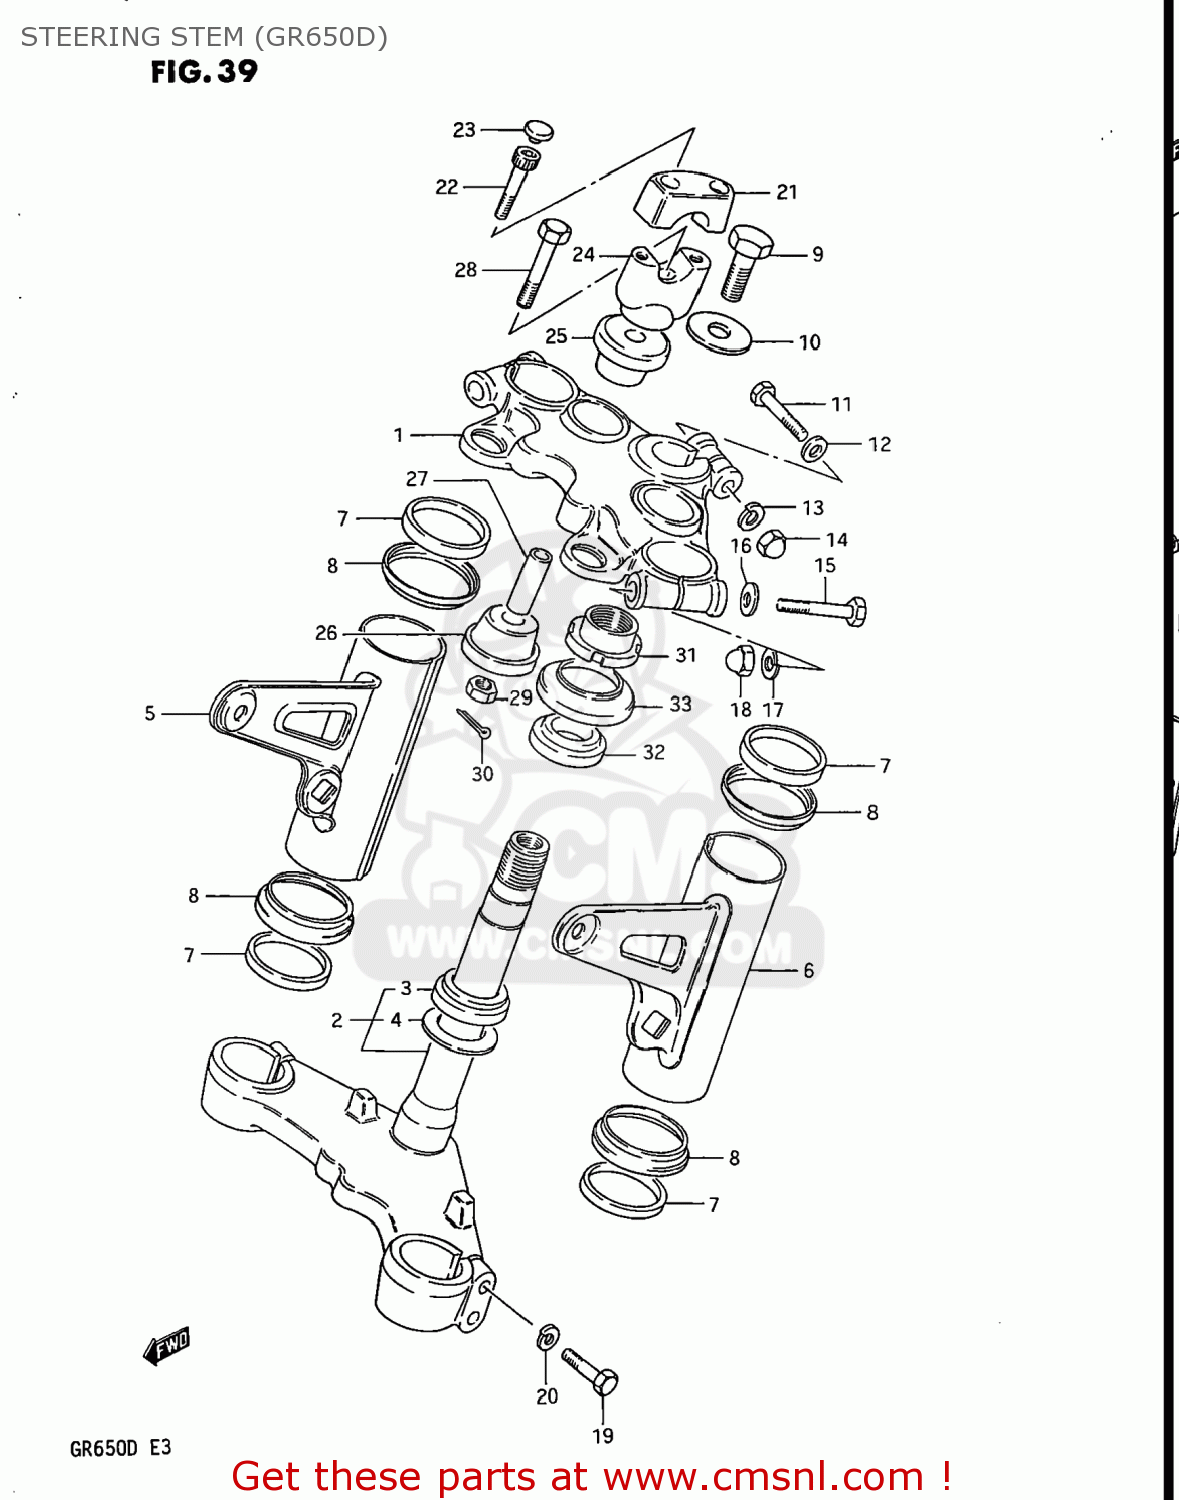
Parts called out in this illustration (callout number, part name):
1	HEAD,STEERING STEM
2	STEM,STEERING
3	BEARING
4	WASHER,THRUST
5	BRACKET COMP,HEADLAMP
6	BRACKET,HEADLAMP,LEFT
7	CUSHION,HEADLAMP BRACKET
8	CAP,HEADLAMP BRACKET
9	BOLT,STEERING STEM HEAD
10	WASHER
11	BOLT 8X50
12	WASHER
13	LOCK WASHER
14	NUT,M8X1.25X12
15	BOLT 10X55
16	WASHER 10MM
17	LOCK WASHER
18	NUT
19	BOLT 8X40
20	LOCK WASHER
21	CLAMP,HANDLE BAR,UPPER
22	BOLT
23	CAP(OD:14.5)
24	CLAMP,HANDLE BAR,LOWER
25	CUSHION,LWR
26	CUSHION,LWR
27	SPACER(10.2X14X46)
28	BOLT(10X78)
29	NUT
30	COTTER PIN
31	NUT,STEERING STEM
32	TAPER,ROLLER BEARING
33	DUST SEAL,STEERING UPR
